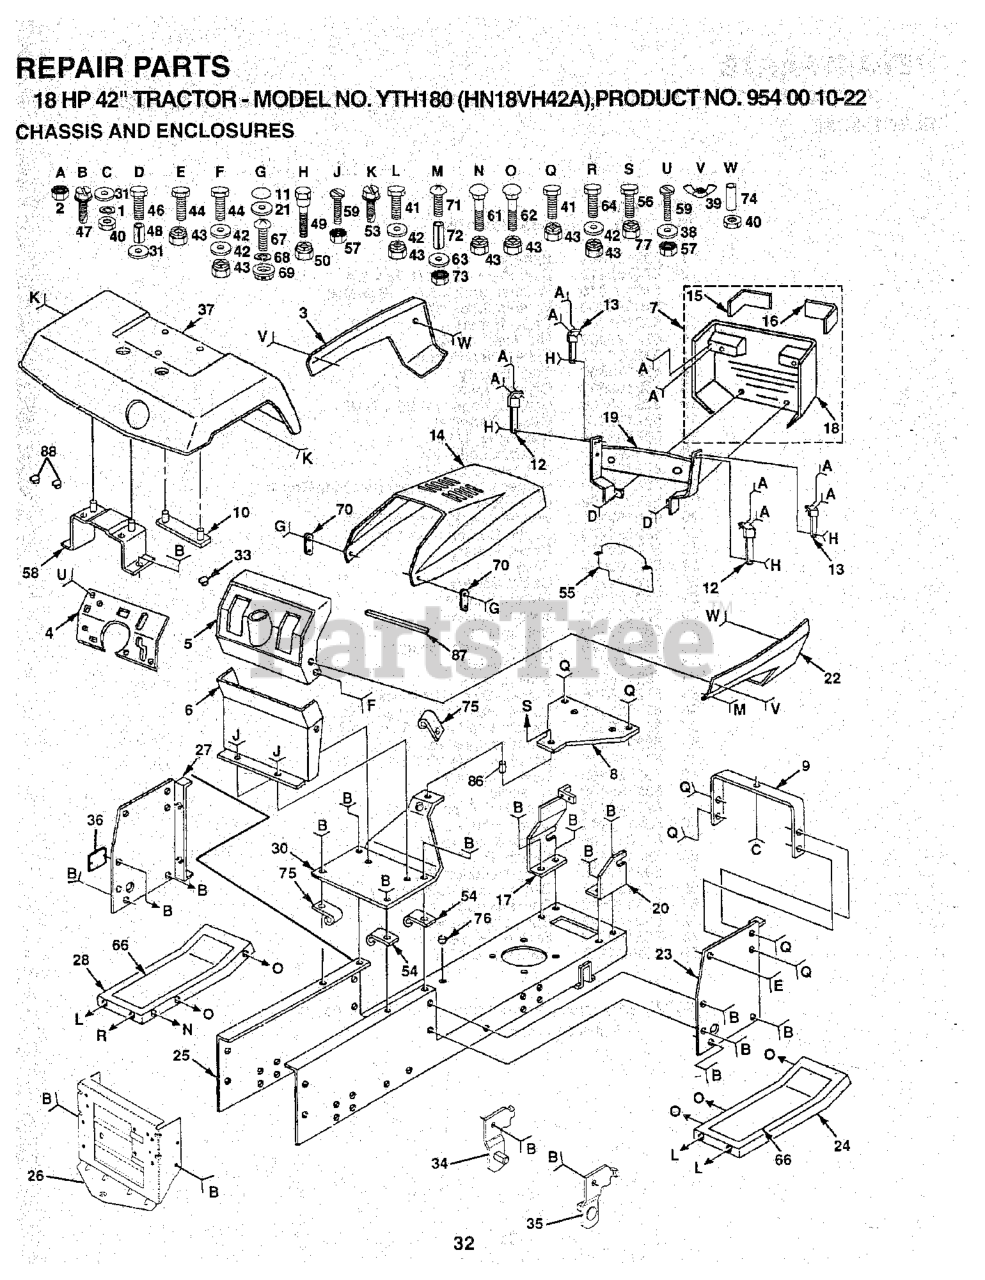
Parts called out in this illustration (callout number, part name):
1	LOCKWASHER
2	NUT
3	SIDE PANEL ASSY LH
4	DASH PLATE
6	DASH LOWER YT NLA
7	GRILL COMPLETE
8	PLATE, BATTERY
9	SUPPORT ASS'Y
10	STRAP
11	SNAP CAP LT
12	STRAP ASSY LT
13	STRAP ASSY LT
14	HOOD
15	LENS LH
16	LENS RH
17	SUPPORT RH YTH
18	GRILL
19	SUPPORT ASS'Y
20	SUPPORT LH YTH
22	SIDE PANEL ASSY RH
23	PANEL DASH RH
24	PAD,SPACER
25	CHASSIS
26	STRETCH DRAWBAR
27	PANEL DASH LH
28	ROLL PIN NLA
31	WASHER PM
33	PLUG-DASH T
34	BRACKET LH PIVOT
35	BRACKET RH PIVOT
36	COVER ACCESS
37	FENDER
38	WASHER
39	WING NUT
40	NUT
42	WASHER
44	BOLT
47	SCREW
49	BOLT T
50	NUT.CROWNLOCK.1/4
53	SCREW LT
54	CLIP,INSULATOR
55	BAFFLE,REAR UPPER
56	Bolt Fin Hex 5/16 - 18 Unc x 2 Gr. 2
57	NUT
58	FENDER BRKT
59	Screw, Machine, Truss Head 5/16-18 UNC x 3/4
61	BOLT D
66	PAD FOOTREST T
67	SCREW
68	LOCKWASHER #10
69	WELDNUT
70	LATCH.HOOD.
71	RP SCREW
73	NUT **
74	SPACER NLA
75	CLIP T
76	SNAP BUSHING T
77	NUT.71038.31-18.HEX.NYLOCK
87	FOAM-STRIP LT
88	NUT-PUSH YT
